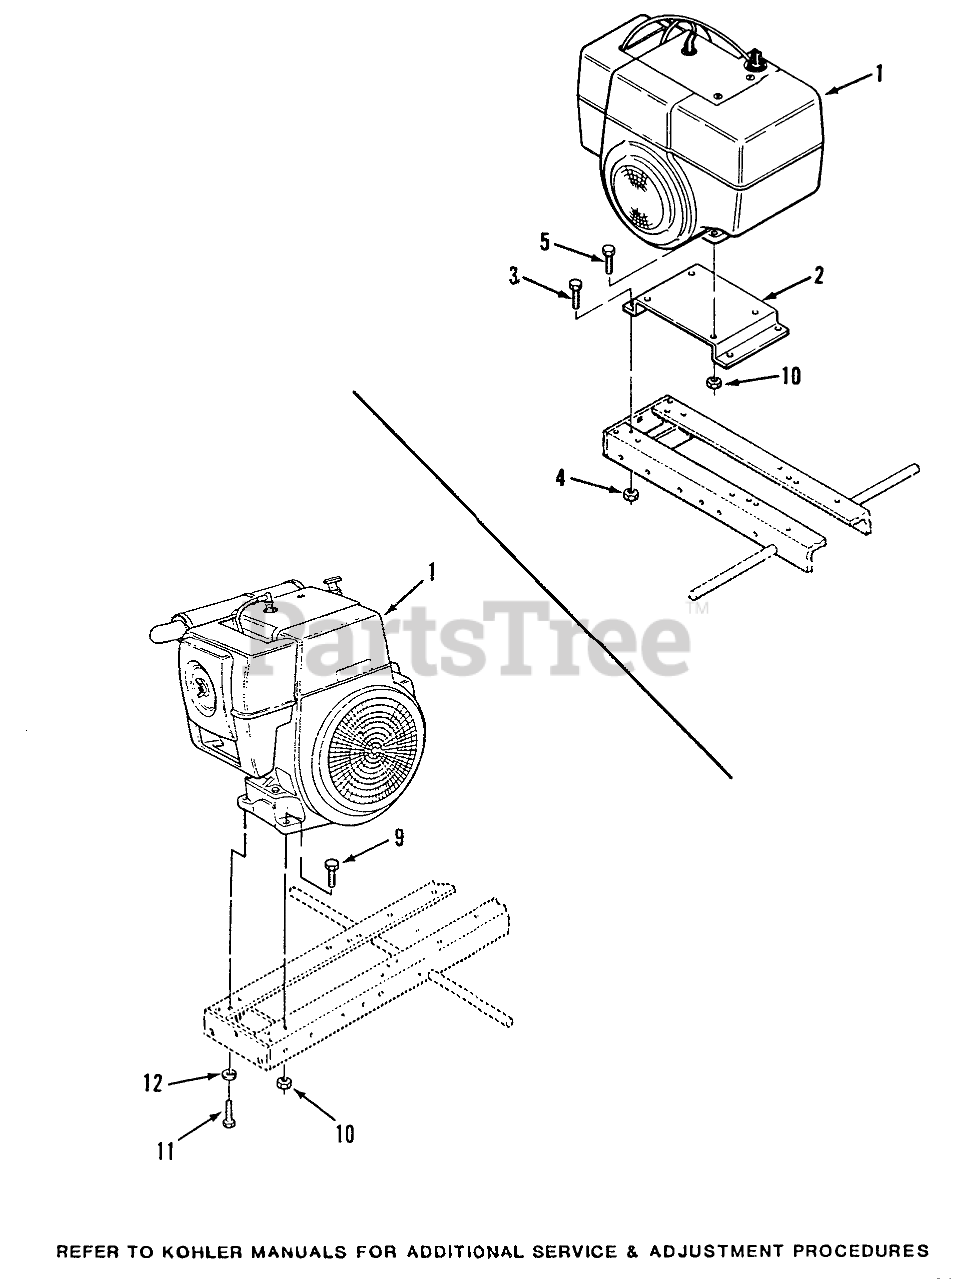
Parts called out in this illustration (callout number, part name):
1	Engine 16HP-Onan P-216-316-8 Only
2	Engine Plate
3	BOLT
4	NUT
5	Bolt
9	BOLT
10	NUT
11	BOLT
12	LOCKWASHER
